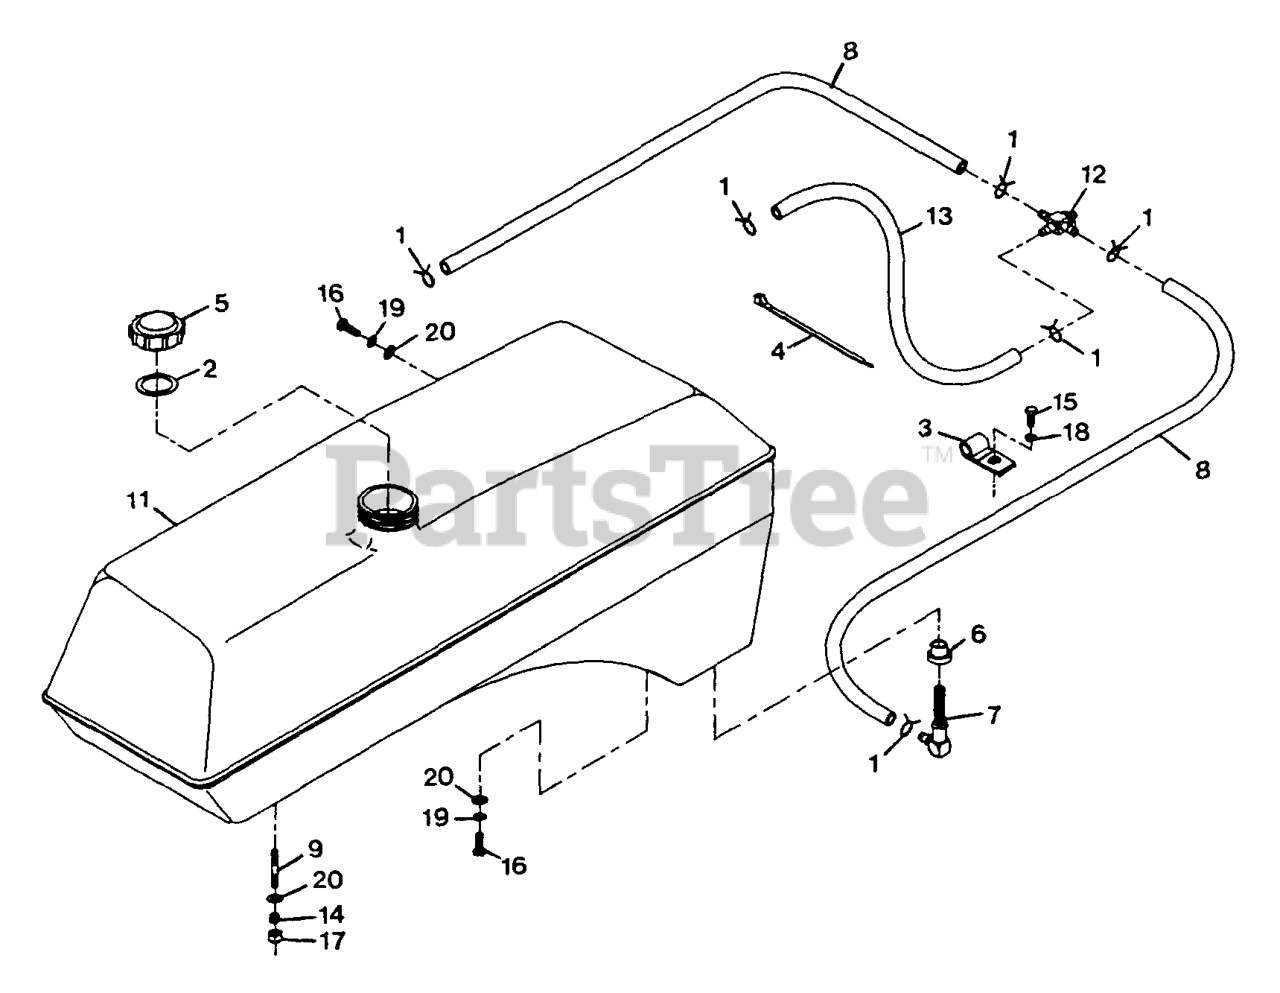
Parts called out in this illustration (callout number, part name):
3	CLIP-LOOM
4	TIE-PLASTIC
5	CAP-FUEL
7	ELBOW-TANK, FUEL
8	HOSE-FUEL
9	STUD
12	VALVE-FUEL
14	SPRING-TANK, FUEL
18	WASHER-LOCK
19	WASHER-LOCK
